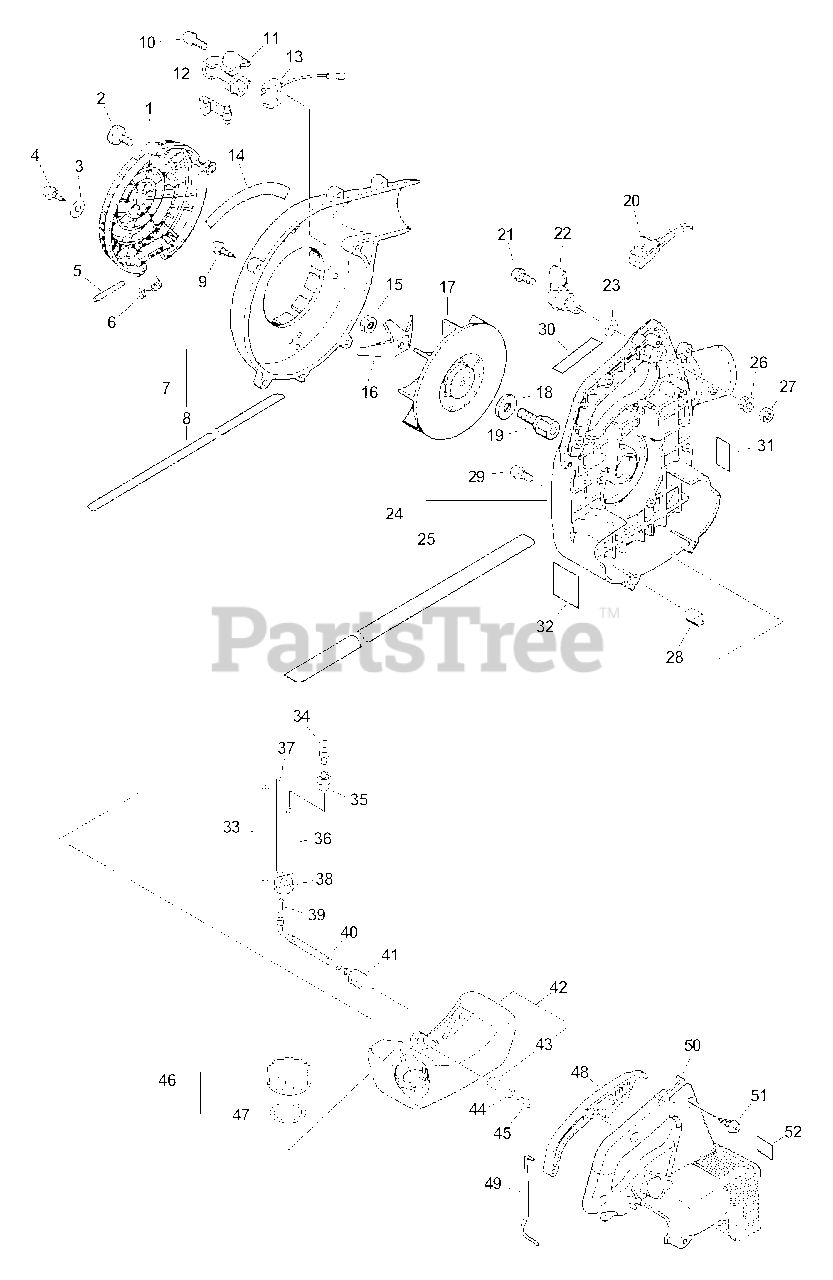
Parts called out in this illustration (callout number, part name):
1	GUARD, DEBRIS
2	THUMBSCREW
3	WASHER - 5
4	SCREW - 5X14
7	FAN COVER ASSY - LEFT
8	CUSHION
9	SCREW - 5X20 -- TAPPING
10	SCREW - 4X22
11	BRACKET, SWITCH - GRAY
12	LEVER, SHUT OFF ACTUATOR
13	IGNITION SWITCH ASSY
14	LABEL - MODEL ES-2400
16	BLADE, SHREDDER
18	WASHER - 8
19	HUB, FAN
20	IGNITION SWITCH ASSY
21	SCREW - 5X25
22	LEVER, THROTTLE - ORANGE
23	WASHER - 5
24	FAN COVER ASSY - RIGHT
25	CUSHION
26	NUT - 5 -- FLANGE
29	SCREW - 4X22
30	LABEL - CAUTION
31	LABEL - CAUTION -- SPANISH
32	LABEL - CAUTION
33	PIPE - 3X6X90 -- CLEAR
34	VENT, FUEL TANK
35	COVER, VENT
36	PIPE - 3X5X70 -- BLACK
37	PIPE - 3X5X90 -- BLACK
38	GROMMET
39	CONNECTOR, PIPE
40	PIPE, FUEL - CORRUGATED
41	FILTER, FUEL
42	FUEL TANK ASSY
44	WASHER - 5
45	SCREW - 5X16
46	CAP ASSY
47	GASKET, CAP
48	TRIGGER, THROTTLE - ORANGE
49	ROD, THROTTLE
50	SCREW - 5X20 -- TAPPING
51	LABEL - HOT SURFACE
52	COVER, ENGINE
